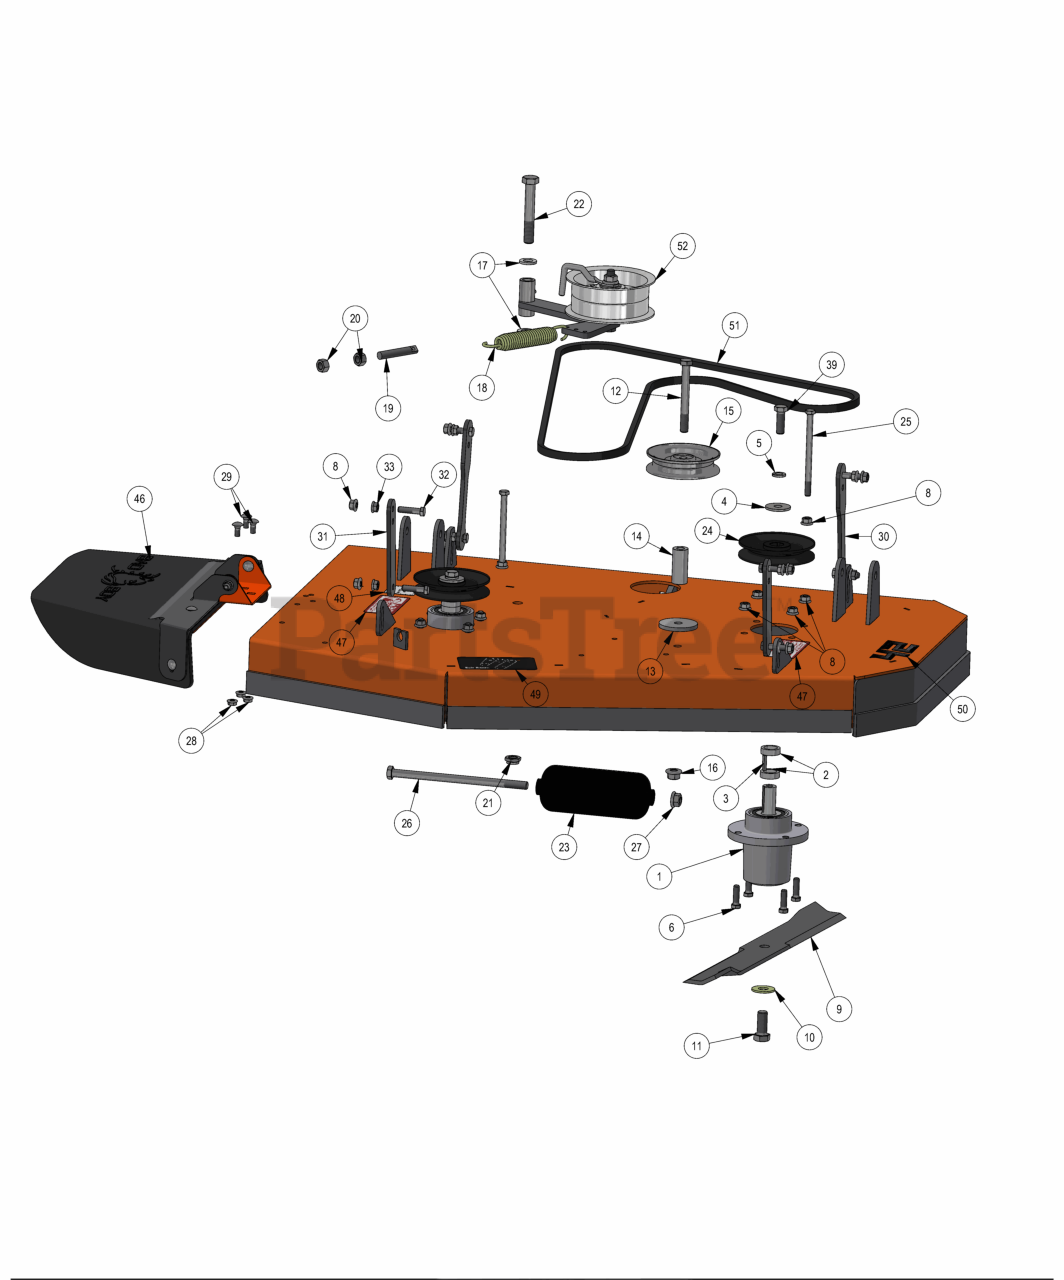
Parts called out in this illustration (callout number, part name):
1	36'' Revolt Spindle Assembly
2	36 Deck Spindle Spacer
3	3/16 X 1 SQ MACHINERY KEY 1018 STL ZINC
4	1/2 BELLEVILLE WASHER (1-5/8 OD X .140 THK) ZINC
5	1/2 SPLIT LOCKWASHER (GR.8) ZINC/YELLOW
6	3/8-16 X 1-1/4 HEX CAP SCREW (GR.5) ZINC
8	3/8-16 NYLON INSERT FLANGE LOCKNUT (GR.F) ZINC
9	60" High Lift Fusion Blade
10	5/8'' Flat Washer
11	5/8-18 X 1-1/2 HEX CAP SCREW (GR.8) ZINC YELLOW
12	1/2-13 X 4-1/2 HEX CAP SCREW (GR.5) ZINC
13	MZ Deck Idler Spacer
14	2019 Revolt Stationary Idle Spacer
15	5 V Idler Pulley 1/2" Bore
16	1/2-13 NYLON INSERT FLANGE LOCKNUT ZINC
17	.635 ID X 1.120 OD X .140 THICK FLAT WASHER NYLON
18	Deck Idler Spring
19	All Thread
20	1/2-13 HEX NUT ZINC
21	5/8-11 NYLON INSERT JAM LOCKNUT ZINC
22	5/8-11 X 4 HEX CAP SCREW (GR.8) ZINC YELLOW
23	3in deck roller
24	60" MZ Deck Pulley (Representation Only)
25	3/8-16 X 5-1/2 HEX CAP SCREW (GR.5) ZINC
26	1/2-13 X 9 HEX CAP SCREW (GR.5) ZINC
27	1/2-13 HEX FLANGE AUTO OVAL LOCKNUT (GR.F) ZINC/WAX
28	5/16-18 HEX SERRATED FLANGE NUT HARD/ZINC
29	5/16-18 x 3/4 Carriage Bolt
30	2019 Stand-On Rear Deck Hanger
31	2019 Revolt Front Deck Hanger
32	3/8-16 X 1-1/2 HEX CAP SCREW (GR.5) ZINC
33	3/8-16 HEX SERRATED FLANGE NUT HARD/ZINC
39	1/2-20 X 1-1/2 HEX CAP SCREW (GR.5) ZINC
40	2024 42 SD Stand On Deck weldment
46	MZ Discharge Chute Assembly
47	Danger Decal-Spindle/Discharge
48	Deck Impact Patent Decal 9591803
49	36" Revolt Deck Belt Route Decal
50	42" Deck Decal
51	2020 Walk-Behind 36 Deck Belt
52	SD Deck Idler Assembly
